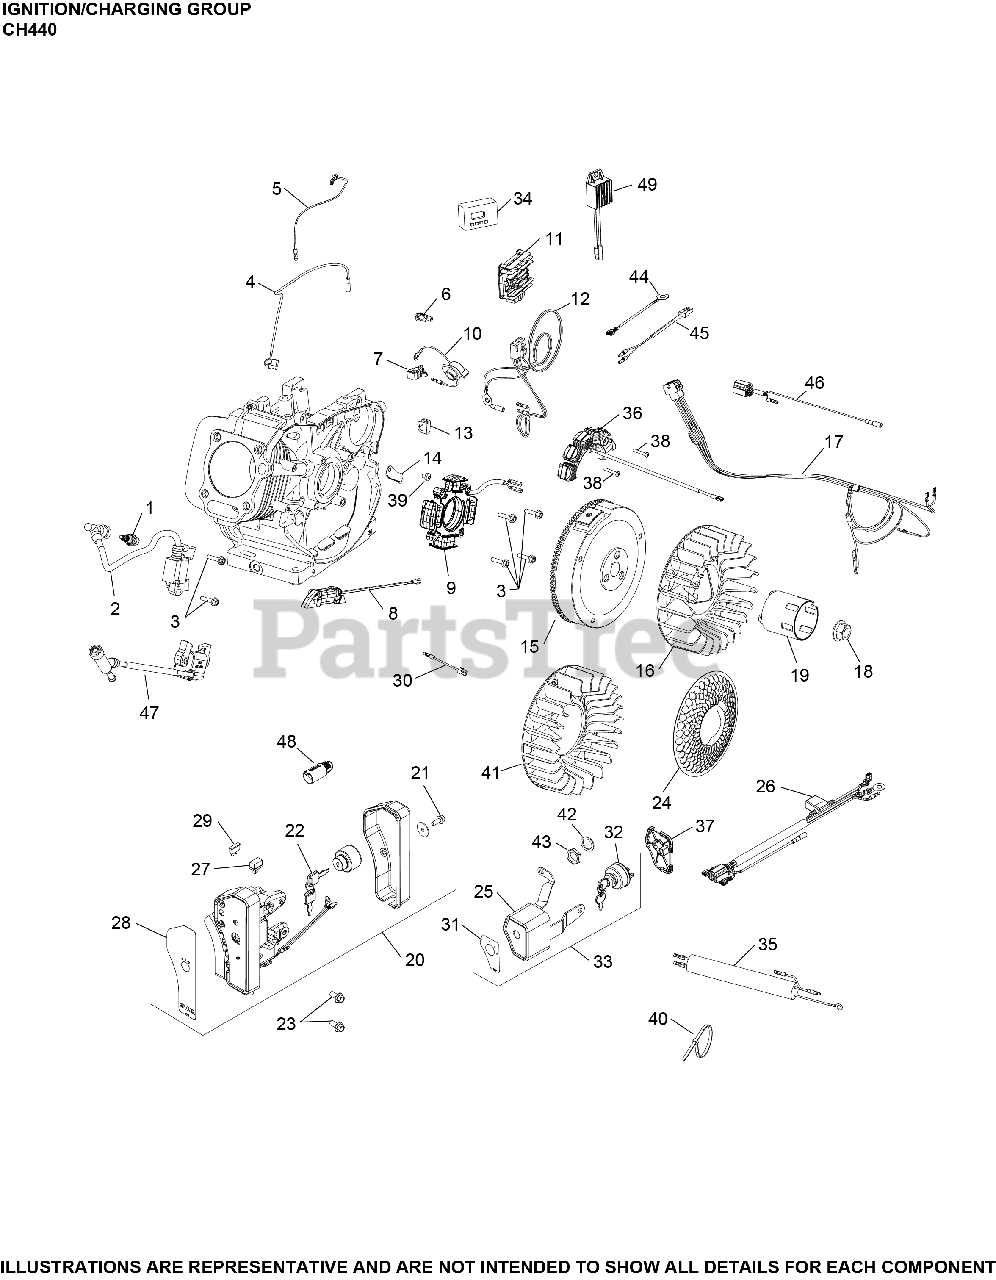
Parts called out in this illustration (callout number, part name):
1	SPARK PLUG
2	MODULE, IGNITION
3	SCREW, M6 X 25 USE 25 086 436-S
4	LEAD, GROUND TO KILL
14	BRACKET, STATOR WIRE
15	FLYWHEEL ASSY ELECTRIC START (CH440)
16	FAN, FLYWHEEL
18	NUT, FLYWHEEL
19	CUP, STARTER DRIVE
36	STATOR ASSEMBLY, 1 AMP
38	SCREW, STATOR MOUNTING (CKY)
39	SCREW, COIL BRACKET (CKY)
